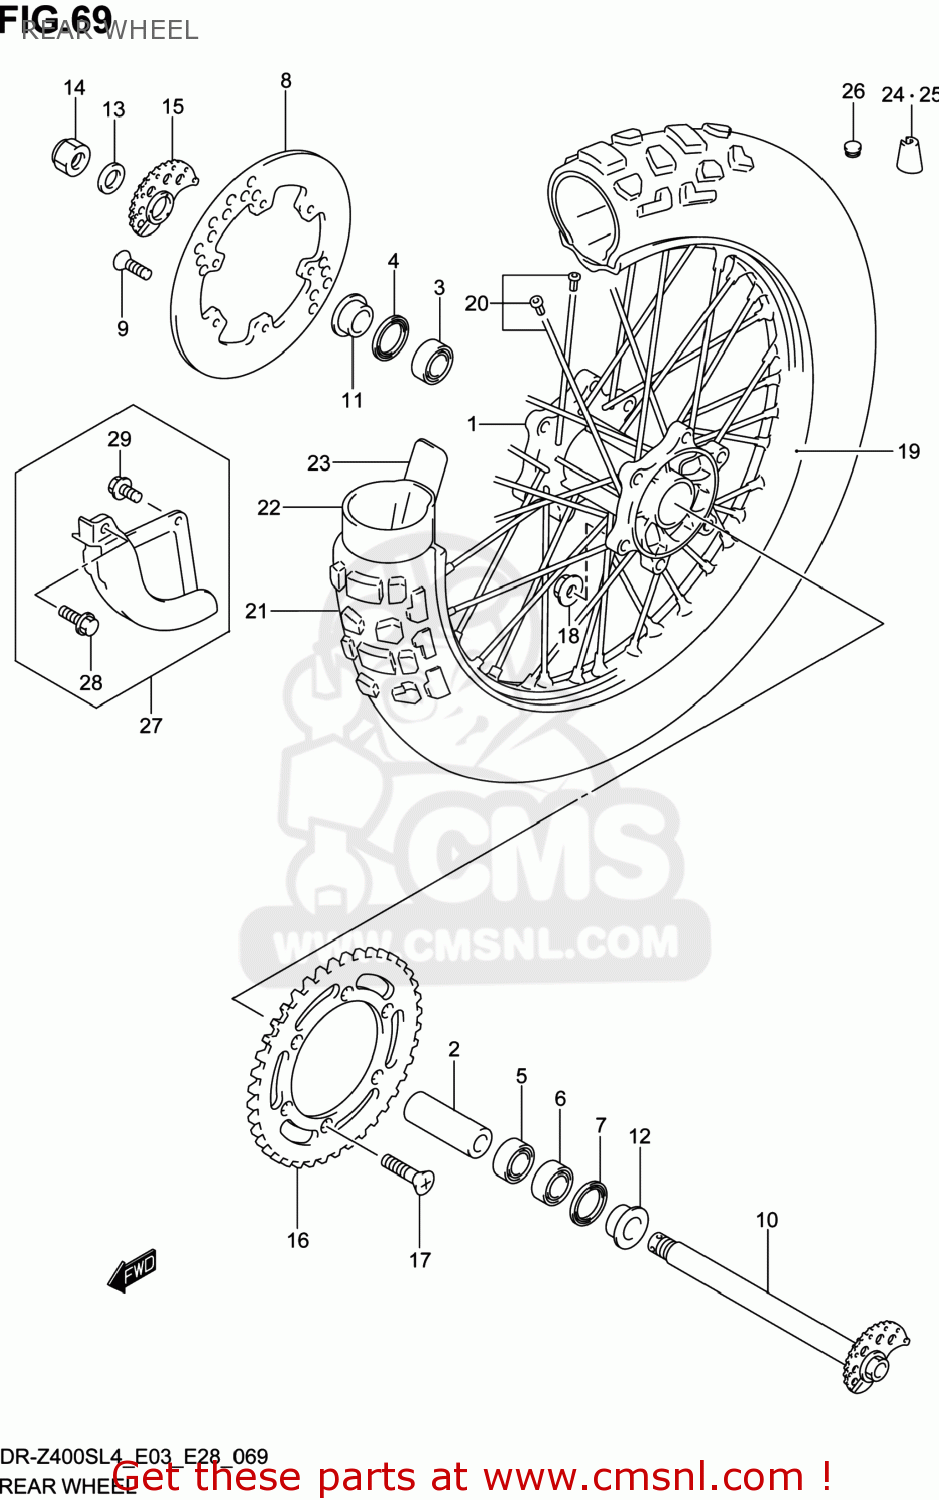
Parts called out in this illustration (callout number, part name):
1	HUB,RR WHEEL
2	SPACER,RR HUB BEARING
3	BEARING
4	SEAL(29X42X6)
5	BEARING
6	BEARING
7	SEAL,OIL(29X47X6)
8	DISC,RR BRAKE
9	SCREW(6X18)
10	AXLE,RR
11	SPACER,RR AXLE
12	SPACER,RR AXLE
13	WASHER(19X32X3.2)
14	NUT
15	ADJUSTER,CHAIN,R
16	SPROCKET,RR(44T,S45C)
17	BOLT(8X30.5)
18	NUT
19	RIM,RR WHEEL(18X2.15 AL)
20	SPOKE SET,RR WHEEL
21	TIRE,RR(120/90-18 65P)
22	TUBE ASSY,WHEEL INNER
23	PROTECTOR,WHL INR TUBE
24	BALANCER,WHEEL(20G)
25	BALANCER,WHEEL(30G)
26	CAP(OD:12)
27	COVER SET,RR BRAKE DISC
28	BOLT
29	BOLT
